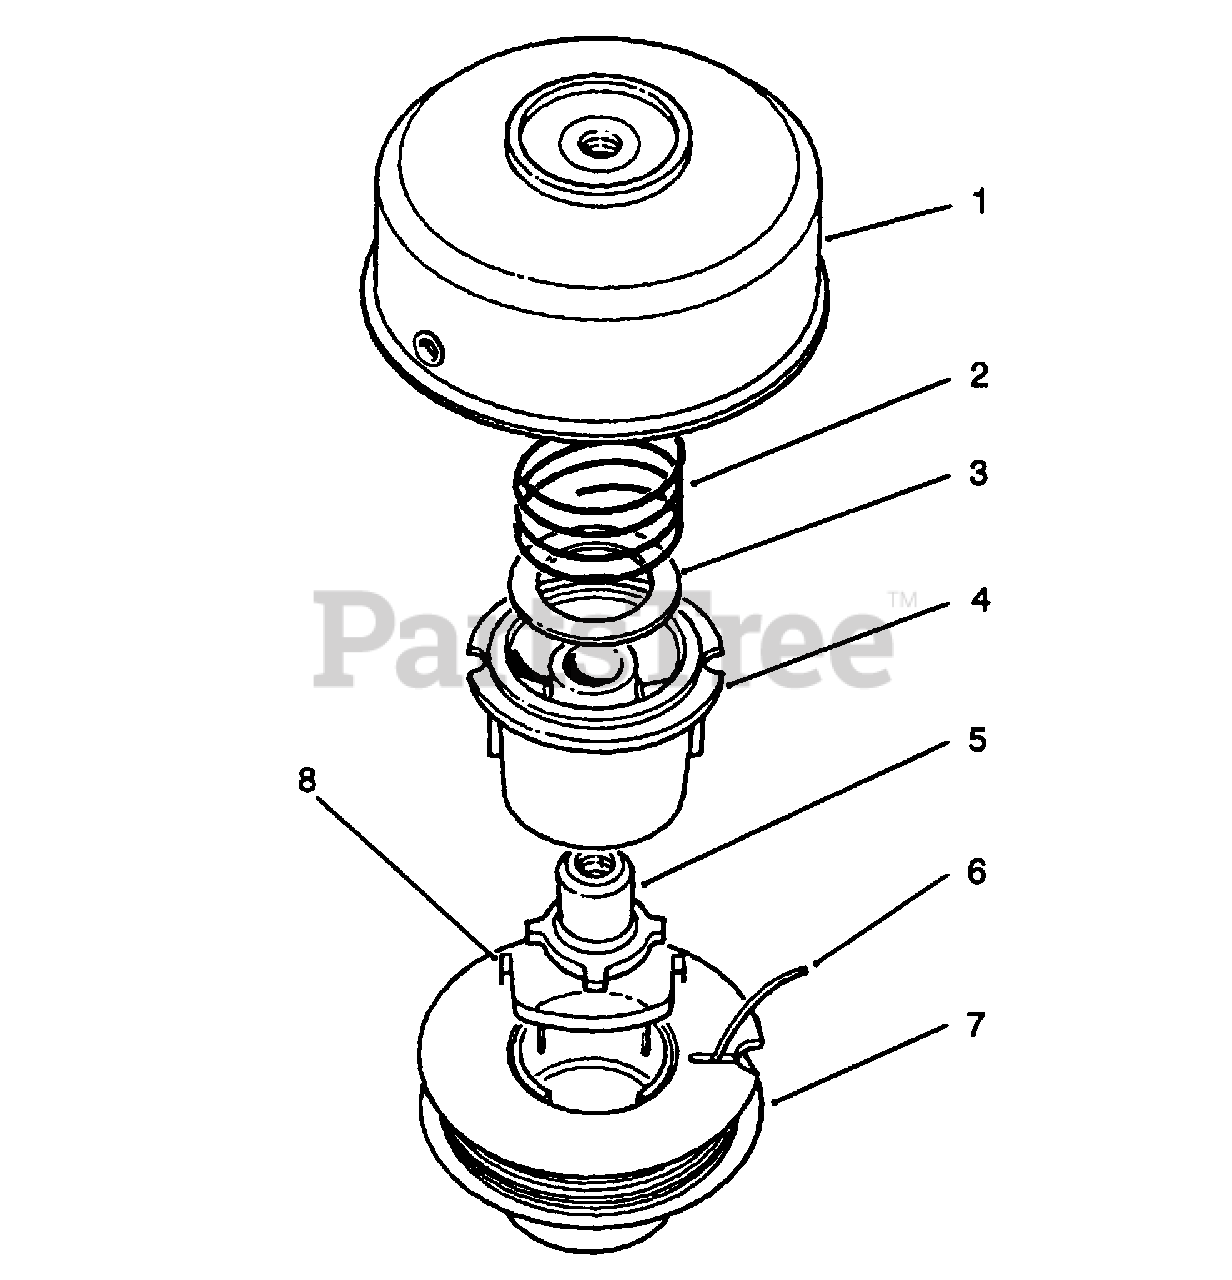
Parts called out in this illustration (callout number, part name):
1	Drum w/Eyelet
4	Core-Spool
5	Driver L.H.
6	Line-Cutting .095 Dia.
7	Spool Prewound .095 Dia. 30' (Incl. Ref. #6 & 8)
8	Saddle-Spool Cap
